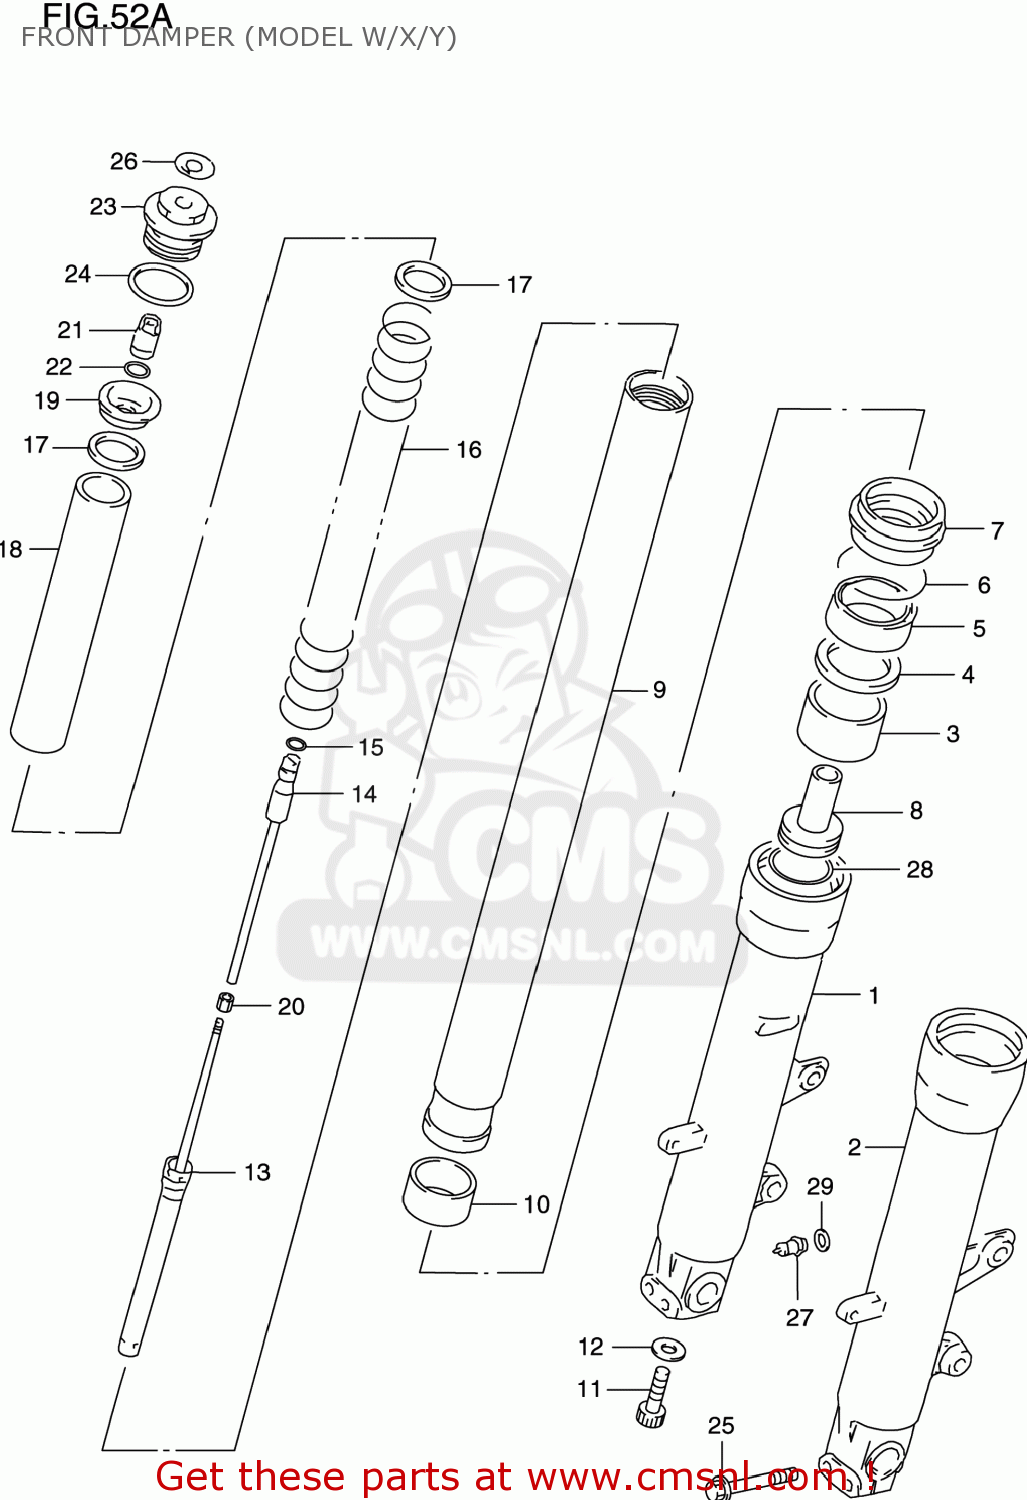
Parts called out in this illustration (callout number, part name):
1	TUBE,OUTER,R
2	TUBE,OUTER,L
3	BUSH,GUIDE
4	SPACER,SEAL
5	SEAL,OIL
6	RING,OIL SEAL STOPPER
7	SEAL,DUST
8	PIECE,OIL LOCK
9	TUBE,INNER
10	BUSH,SLIDE
11	BOLT
12	WASHER(10X15X1.5)
13	ROD,FRONT DAMPER
14	ROD,ADJUST
15	O RING(D:1.9,ID:3.8)
16	SPRING,FR
17	JOINT,SPRING
18	COLLAR,SPRING
19	SEAT,SPRING UPR
20	NUT
21	ADJUSTER,SPRING
22	O RING(D:2.5,ID:13.8)
23	BOLT,FORK
24	O RING
25	BOLT
26	LABEL
27	PIECE,ADJUST
28	O RING
29	LABEL,ADJUST PIECE LWR
